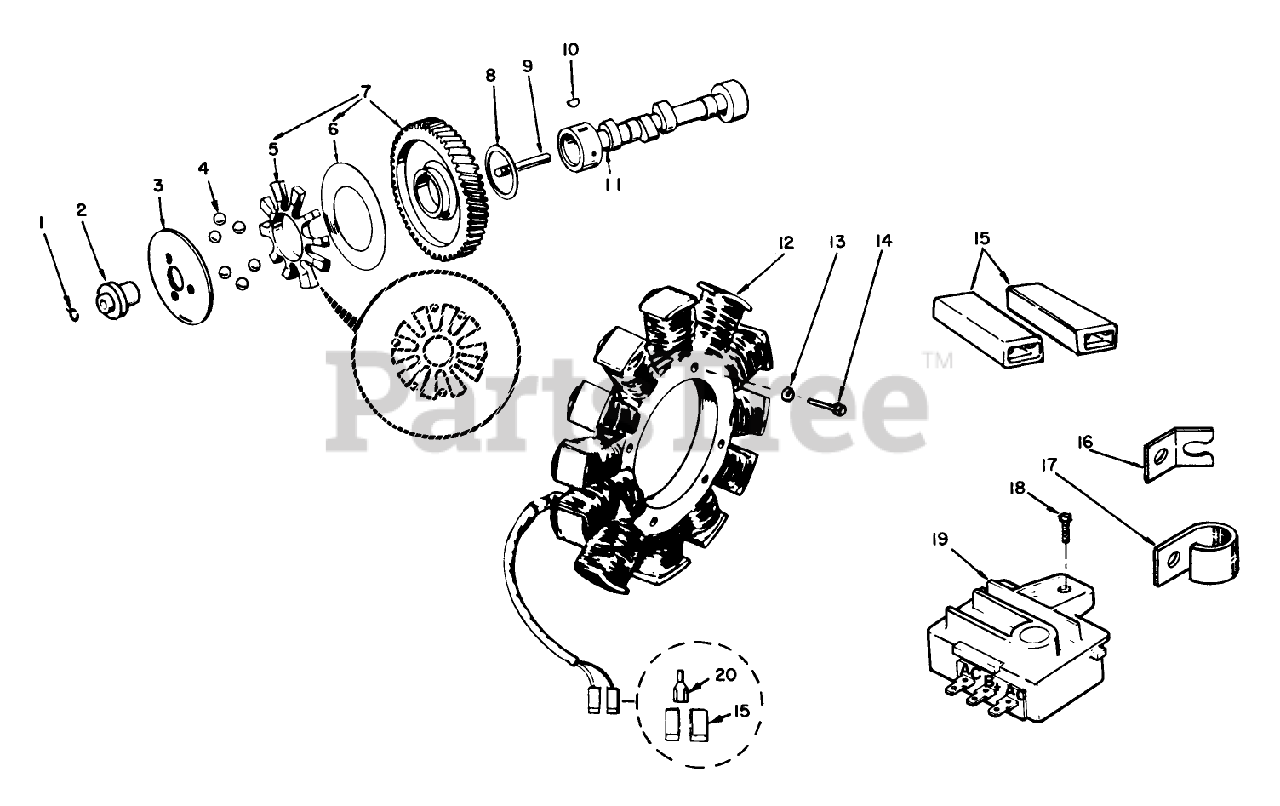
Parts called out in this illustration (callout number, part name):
2	HUB-GOVERNOR CUP
3	CUP-GOVERNOR
4	BEARING
5	Spacer, Flyball
6	Plate, Flyball
7	Gear, Camshaft (Incl. Ref. #5 & 6)
8	WASHER-THRUST
9	PIN-CENTER
11	Camshaft (Incl. Ref. #9)
12	Stator (Incl. Ref. #15 & 20)
13	WASHER-LOCK
14	Screw
15	TERMINAL CONN. BODY
16	BRACKET
17	WIRE CLAMP
18	HX WSHR HD CAPSCREW
19	REGULATOR
20	TERMINAL
